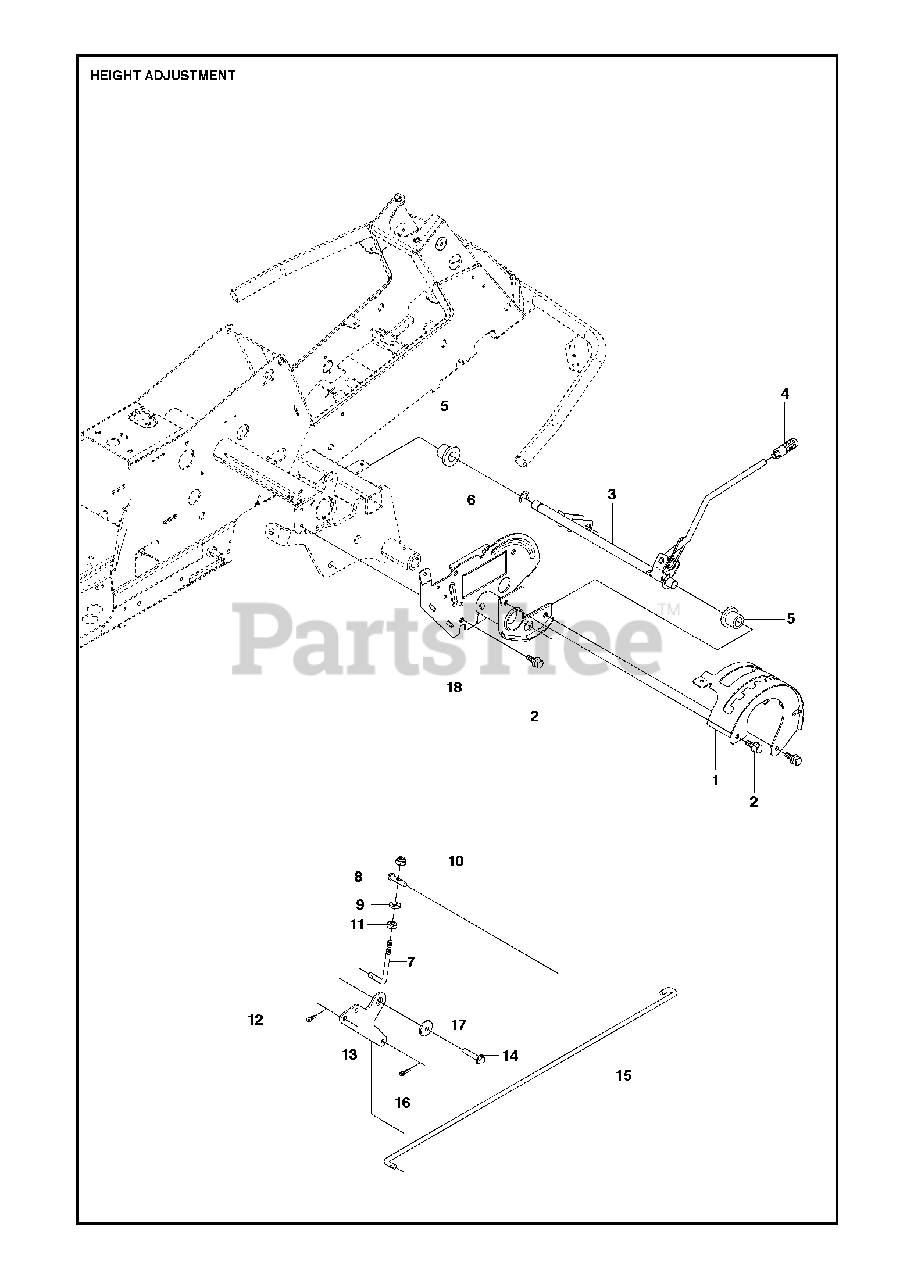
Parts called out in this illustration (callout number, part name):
4	GEAR STICK KNOB
5	BUSHING
9	WASHER
10	LOCKNUT M8
11	NUT
12	SPLIT PIN
14	BOLT
16	SPLIT PIN
17	WASHER
